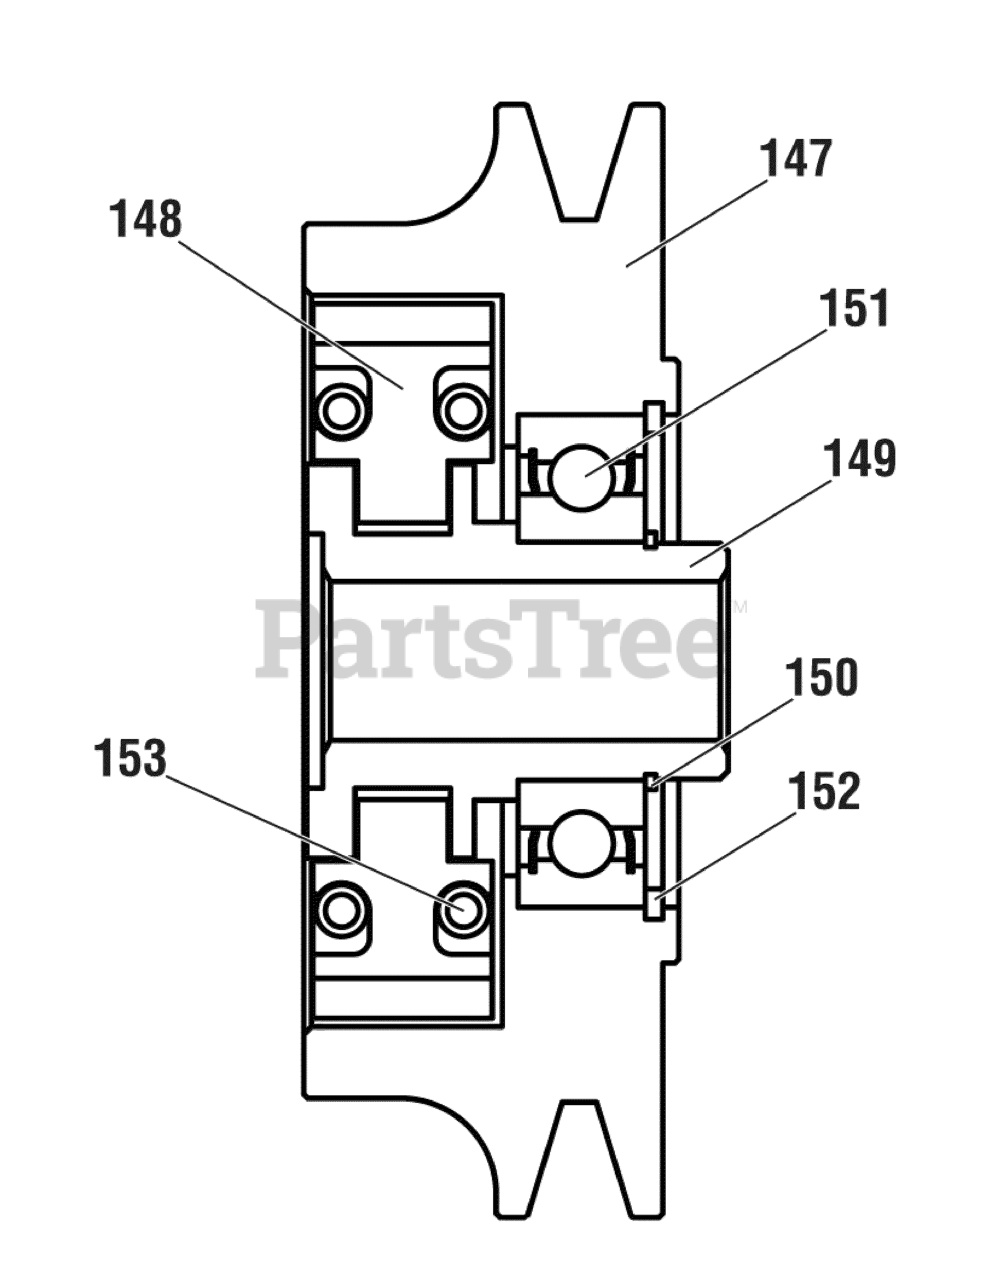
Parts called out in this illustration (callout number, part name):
147	CLUTCH, Outer
148	CLUTCH CORE, ZG270-500
149	FRICTION PLATE, Clutch
150	RING-SHIELD, 30
151	BEARING, 6206-2RS
152	CIRCLIP, Internal, 62
153	SPRING, Clutch
